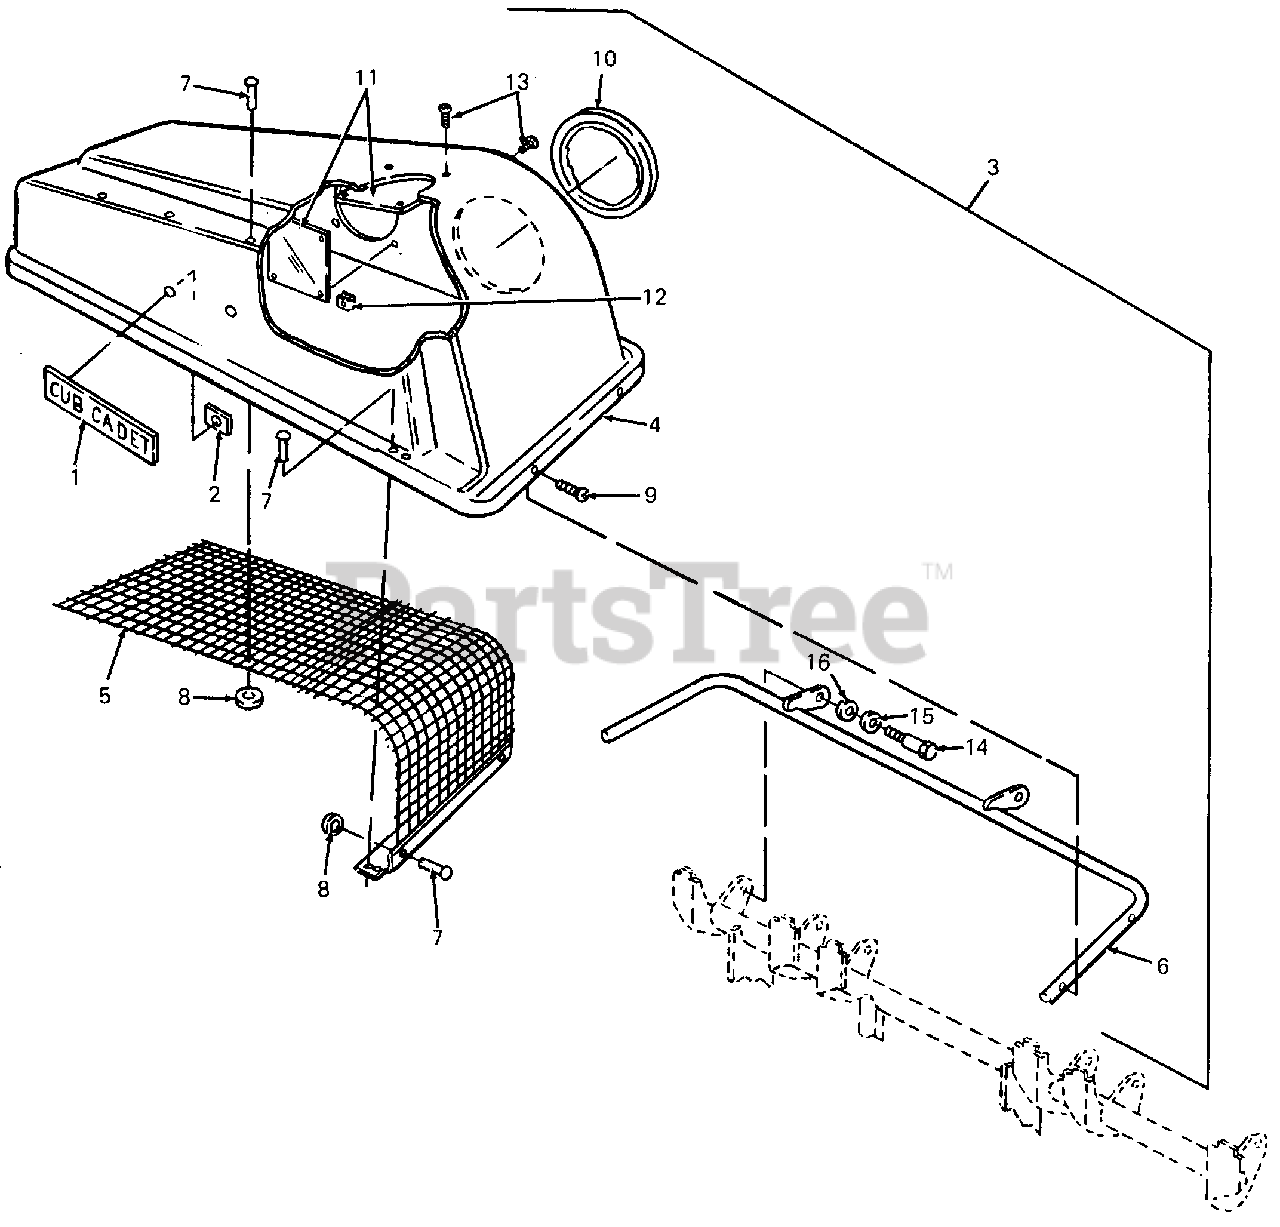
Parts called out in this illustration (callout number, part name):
1	Plaque, Logo w/Studs
2	Nut, Push-on Speed
3	Cover Assy, Grass Catcher
8	Washer, Flat, .218 X .62 X .063
9	Screw, Hex Wash. Hd. Tapp, 1/4 X .50 Lg
10	Seal, Tube, 8.1 ID
11	Plate, Plastic, 1/8 Thk X 5.62 Sq
12	Nut, U-Type Speed
13	Screw, Truss Mach., #10 X .50 Lg
14	Screw, Shld
15	Washer, Flat, .510 X .75 X .033
16	Washer, Bell, .515 X 1.14
